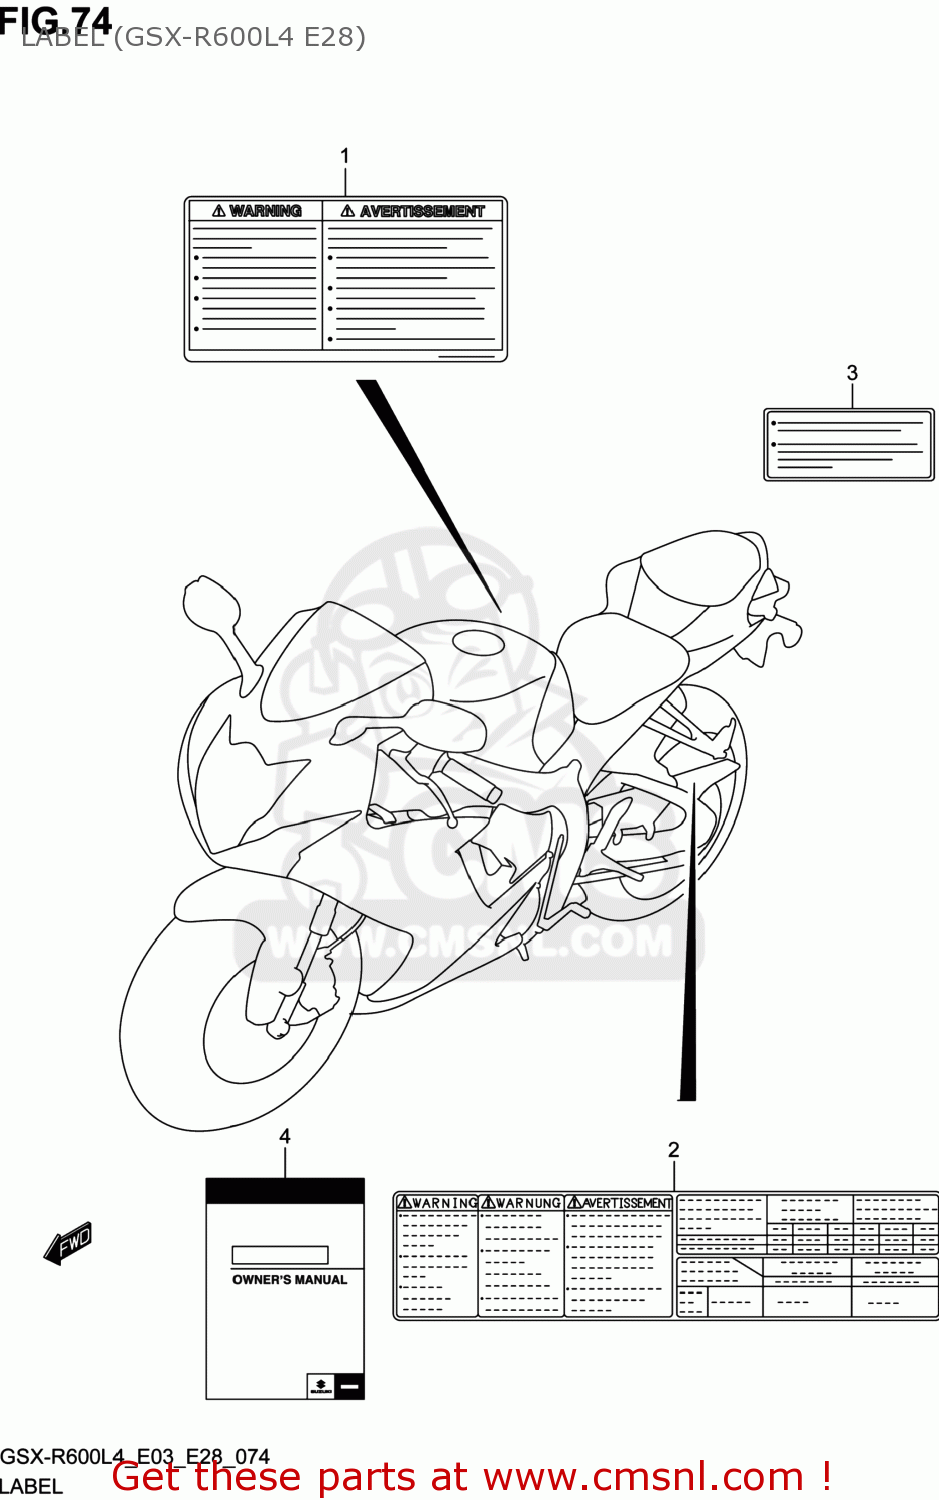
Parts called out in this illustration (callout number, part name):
1	LABEL,GENERAL WARNING
2	LABEL,TIRE INFORMATION
3	LABEL,FUEL INFORMATION
4	MANUAL,OWNER'S
